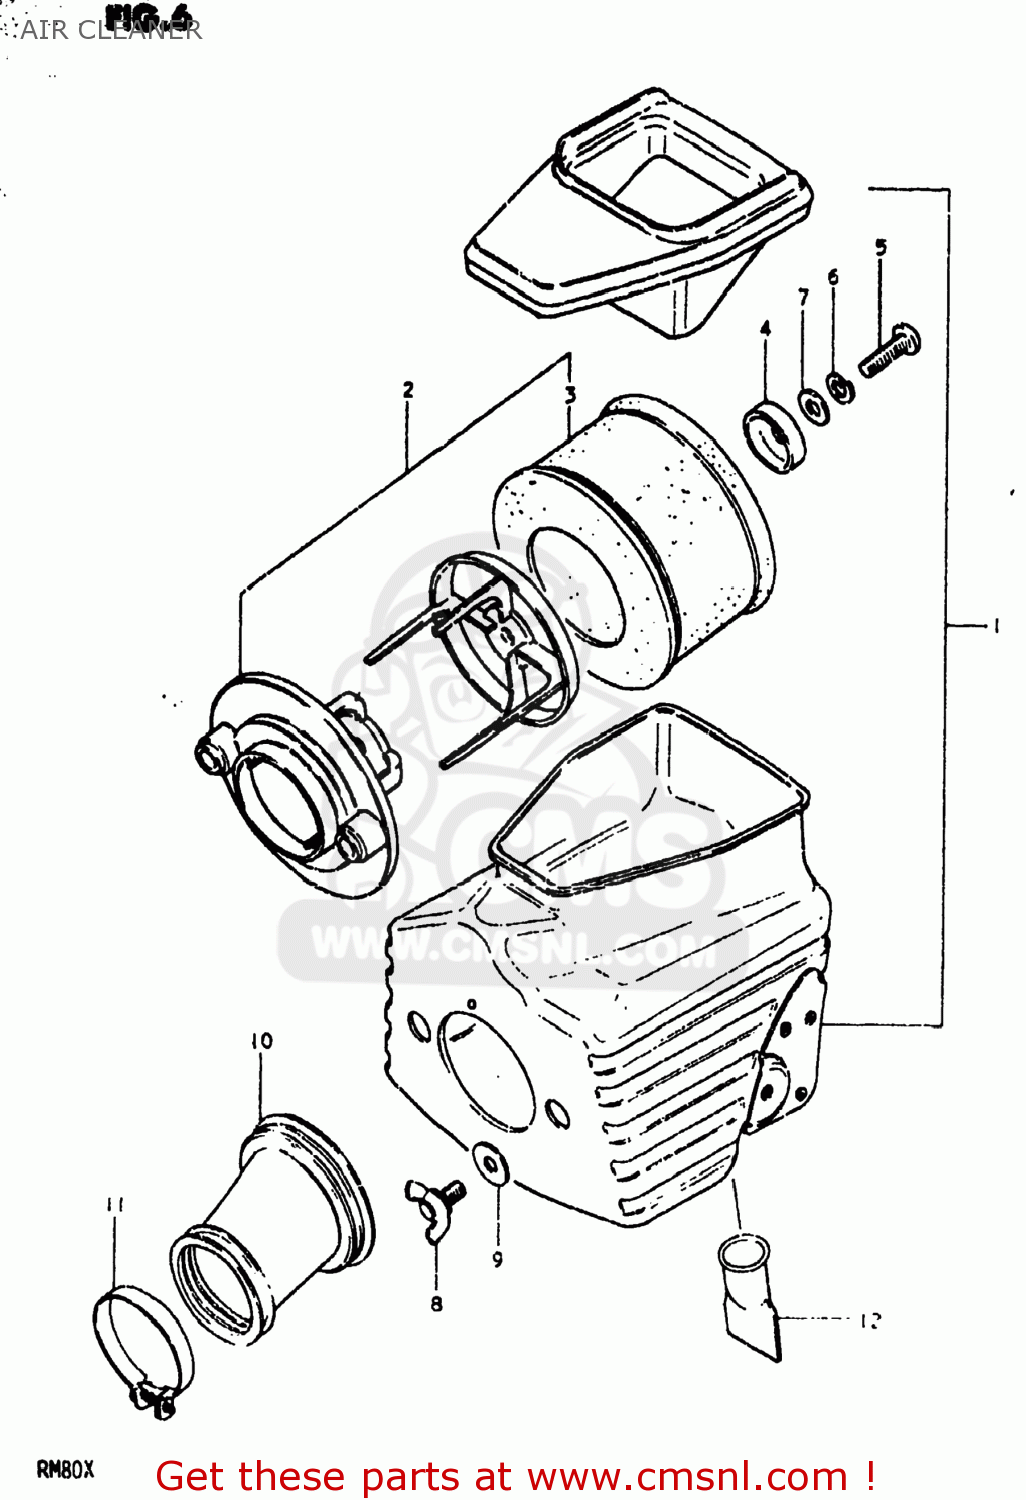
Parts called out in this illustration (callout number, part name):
1	CLEANER ASSEMBLY,AIR
2	FILTER,AIR CLEANER
3	FILTER
4	HOLDER,FILTER
5	SCREW
6	LOCK WASHER
7	WASHER
8	WING BOLT
9	SPACER,AIR CLEANER,REAR
10	HOSE,AIR CLEANER OUTLET
11	CLAMP
12	DRAIN TUBE
